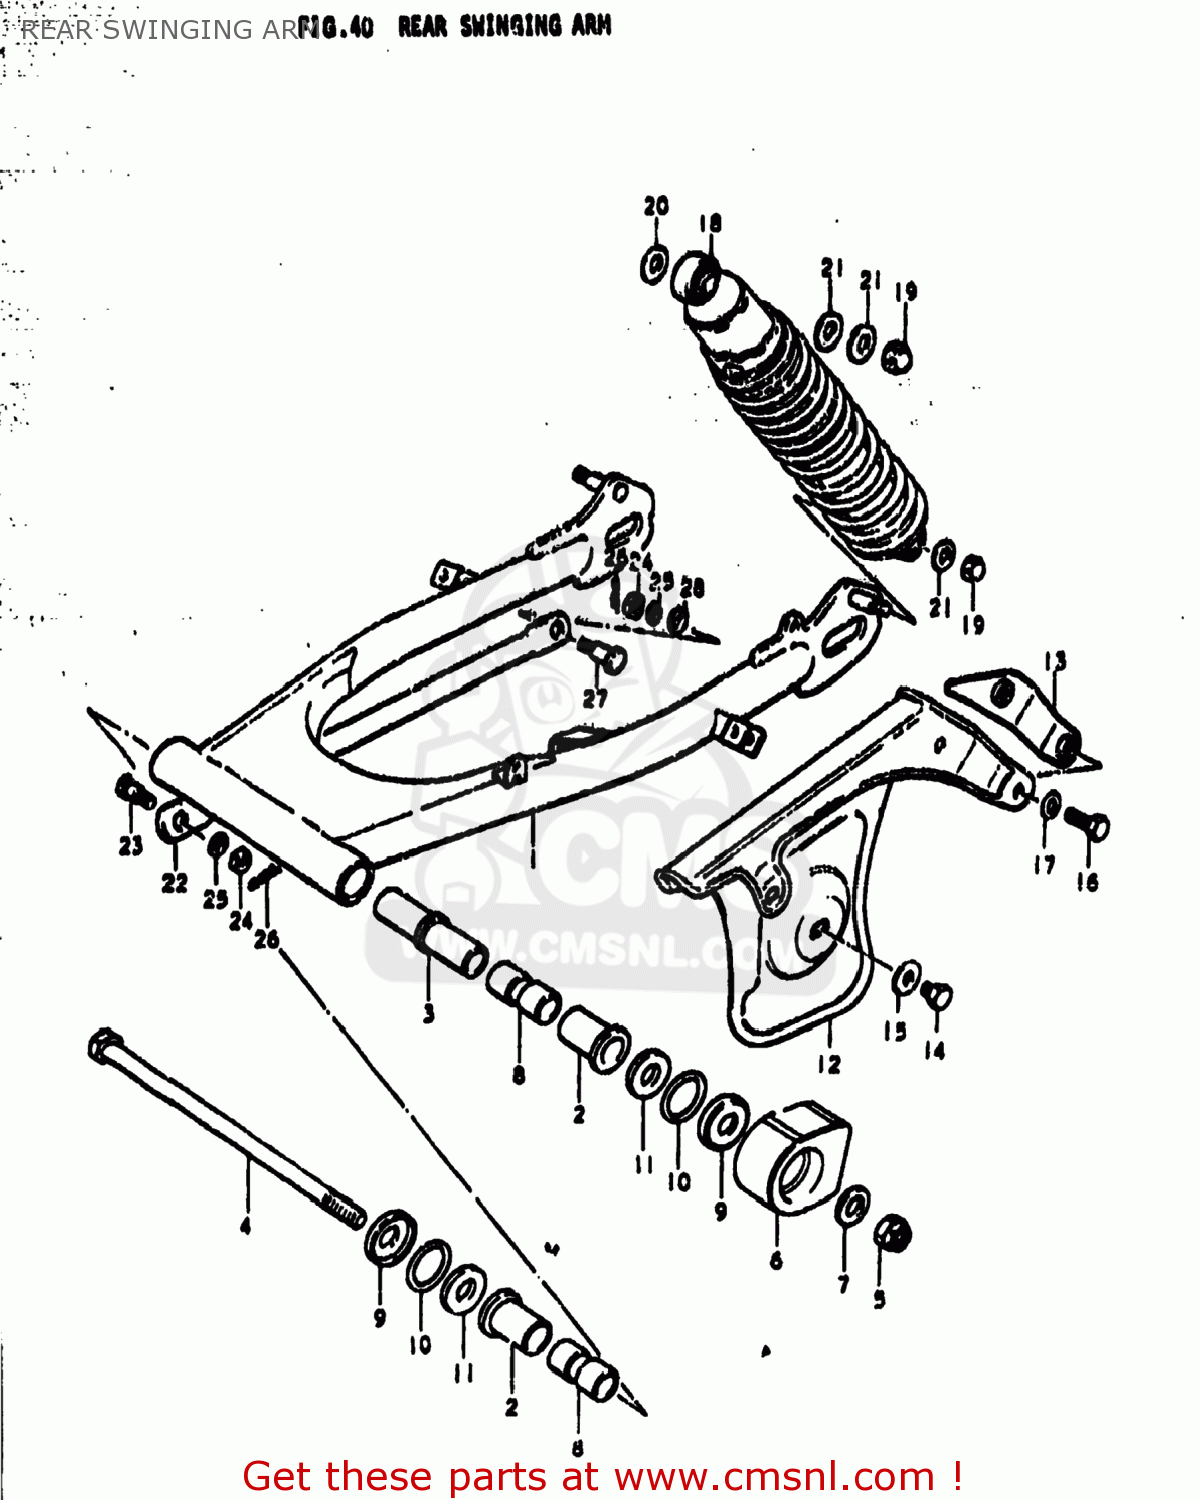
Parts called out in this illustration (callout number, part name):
1	SWING ARM ASSEMBLY,REAR
2	BUSH
3	SPACER,RR SWGARM PIVOT CTR
4	SHAFT,REAR SWING ARM
5	NUT
6	BUFFER,CHAIN TOUCH DEFENSE
7	WASHER
8	SPACER,RR SWGARM PIVOT
9	COVER,SWGARM BUSH DUST SEAL
10	O RING(D:2,ID:24.5)
11	WASHER(12.5X24X2.3)
12	CASE,CHAIN
13	REINFORCEMENT,CHAIN CASE
14	BOLT(6X8)
15	WASHER
16	BOLT, UPPER
17	WASHER
18	ABSORBER ASSEMBLY,REAR SHOCK
19	NUT, LOWER LH
20	WASHER
21	WASHER
22	TORQUE LINK,REAR
23	BOLT(8X26.5)
24	NUT
25	LOCK WASHER
26	CLIP
27	BOLT(8X22)
28	WASHER
